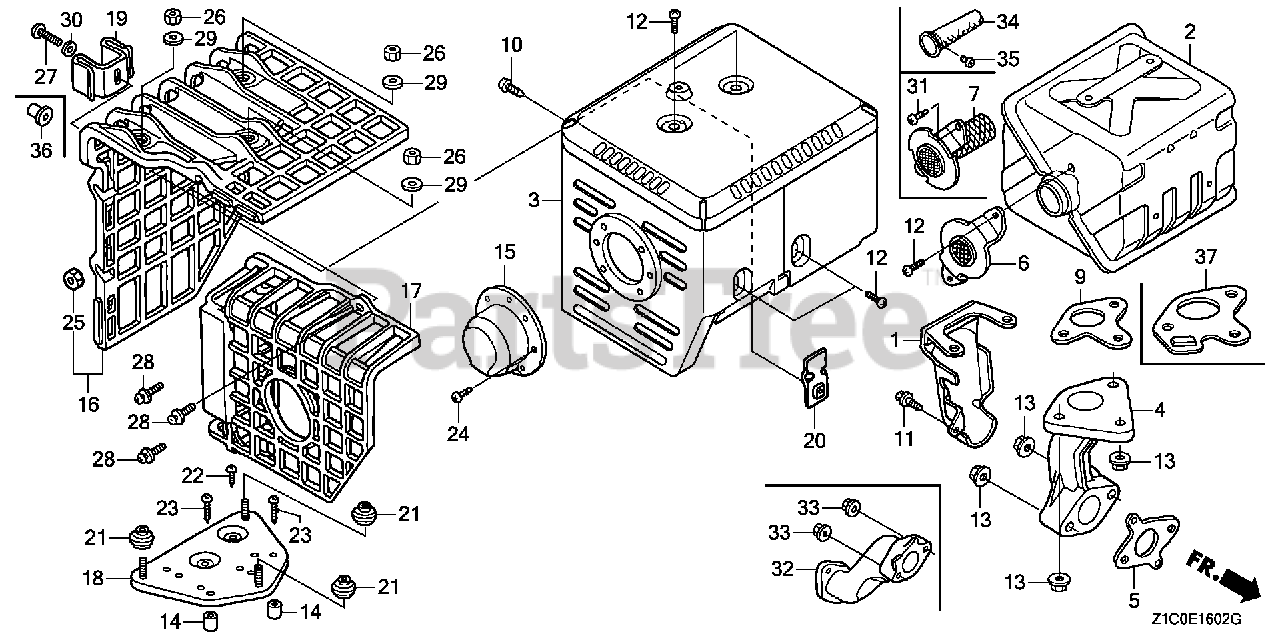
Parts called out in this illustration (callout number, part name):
1	PROTECTOR, EX. PIPE
2	MUFFLER
3	PROTECTOR, MUFFLER
5	GASKET, EX. PIPE
6	FLANGE, BAFFLE
7	ARRESTER, SPARK
9	GASKET, MUFFLER
9	GASKET, MUFFLER (NIPPON LEAKLESS)
9	GASKET, MUFFLER (THAI LEAKLESS)
10	SCREW, TAPPING (6X10)
11	BOLT, FLANGE (6X12) (CT200)
12	SCREW, TAPPING (5X8)
13	NUT, FLANGE (8MM)
